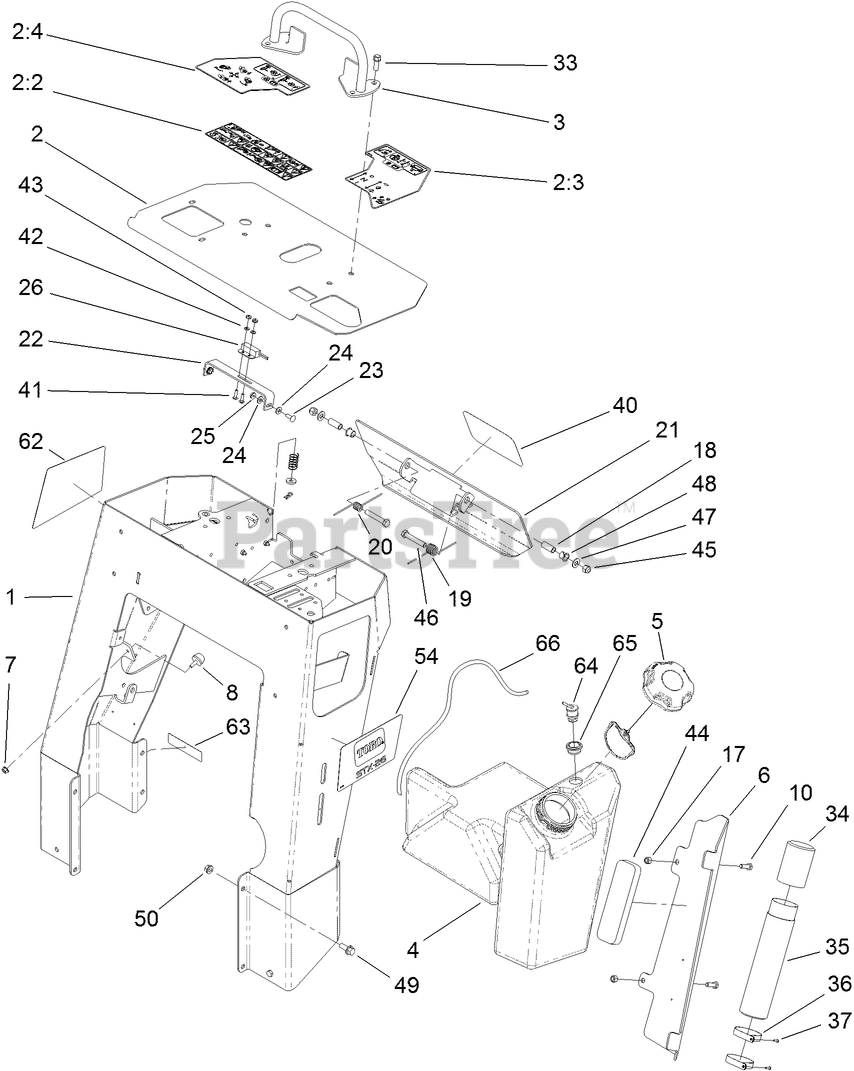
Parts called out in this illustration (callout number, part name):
2	CONTROL PANEL ASM
2:2	DECAL-WARNING
2:3	DECAL-CONSOLE, LH
2:4	DECAL-CONSOLE, RH
3	BAR-REFERENCE
4	TANK-FUEL
5	CAP-FUEL, RATCHETING
6	BRACKET-COVER, TANK
7	NUT-HF
8	BUMPER
10	SCREW-HH
17	NUT-LOCK, NI
18	SPACER-SPRING
19	SPRING-TORSION, LH
20	SPRING-TORSION, RH
21	PLATE-REVERSE
22	PLATE-SWITCH
23	BOLT-CARR
24	WASHER-FLAT
25	NUT-KEPS
26	SWITCH-PROXIMITY
33	SCREW-TAPTITE
34	CAP-HOUSING
35	TUBE-MANUAL
36	CLAMP-R
37	RIVET-POP
41	SCREW-CARR
42	WASHER-FLAT
43	NUT-KEPS
44	PAD-FOAM
45	NUT-LOCK, NI
46	SCREW-HH
47	WASHER-FLAT
48	BUSHING-NYLINER
49	SCREW-HHF
50	NUT-FLANGE
54	DECAL-SIDE, LH
62	DECAL-SIDE, RH
63	DECAL-ARRESTER, SPARK
64	VALVE-ROLLOVER
65	GROMMET
66	HOSE-VENT, TANK
